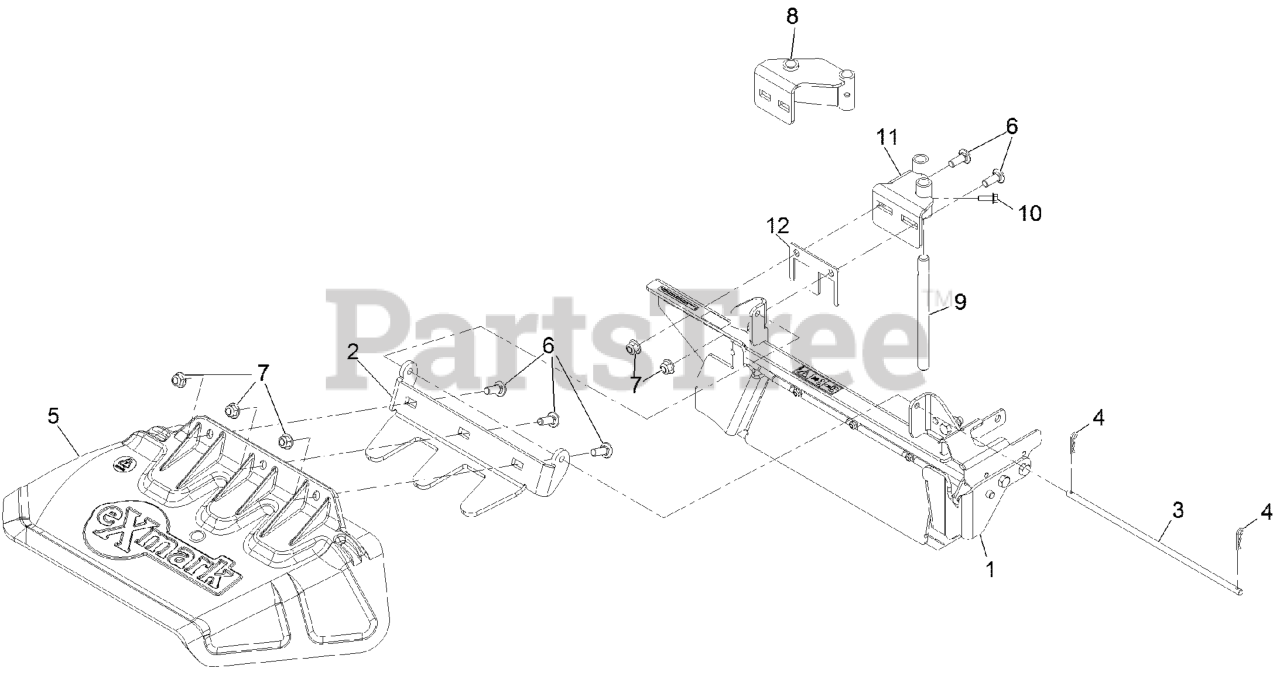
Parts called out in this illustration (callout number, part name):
1	ASM, Ocd Gate
2	MOUNT, DISCHARGE CHUTE
3	PIN,CHUTE
4	PIN-COTTER
5	CHUTE,DISCHARGE
6	SCREW-CARR
7	NUT-HF, NI
8	Ocd Mount ASM [red]
9	PIN-MOUNT, OCD
10	SCREW-HHF
11	WELDMENT, OCD MOUNT
12	SHIM-OCDWB
